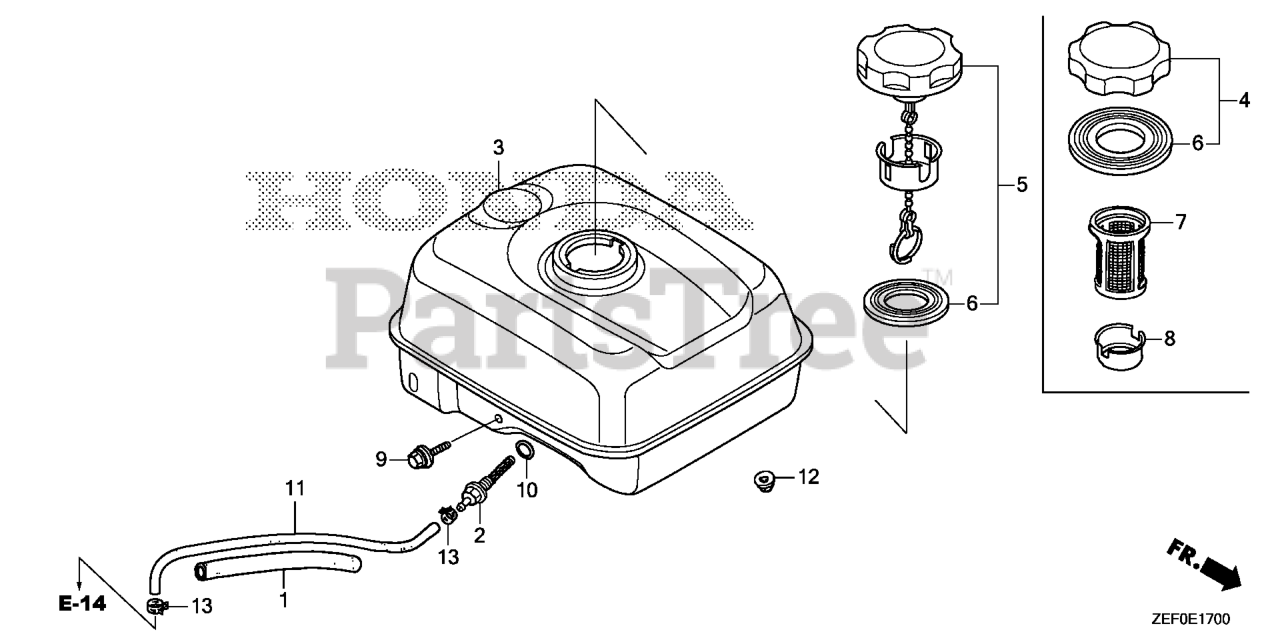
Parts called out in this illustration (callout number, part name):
1	RUBBER, SUPPORTER (107MM)
2	JOINT, FUEL TANK
3	TANK, FUEL *NH31* (MCKINLEY WHITE)
3	TANK, FUEL *NH1* (BLACK)
5	CAP, FUEL FILLER
6	GASKET, FUEL FILLER CAP
6	GASKET, FUEL FILLER CAP (39X62X3) (TOUYOUSYA)
9	BOLT, FLANGE (6X34)
10	O-RING (14MM)
11	TUBE, FUEL (4.5X145)
12	NUT, FLANGE (6MM)
13	CLIP, TUBE (D8)
